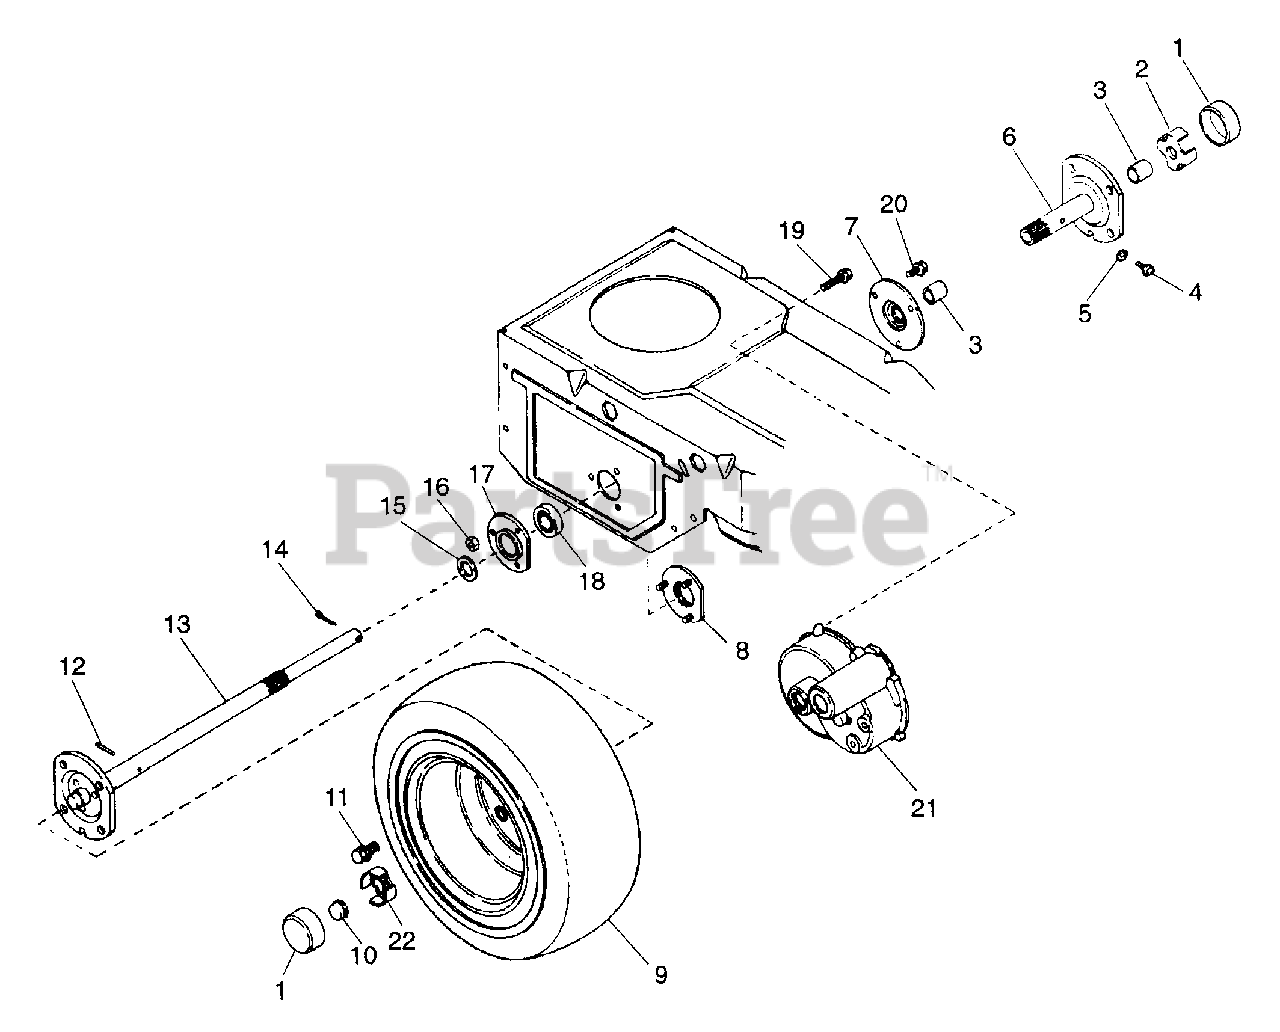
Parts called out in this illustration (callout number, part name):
1	HUB CAP
2	SPINDLE CUP
3	BSHG-SLV .690X.814X1.000 BR
4	SPIN DRIVE ZERK FITTING
5	WSHR-LK .250X.047 LT PL
6	L.H. AXLE ASSEMBLY
7	SEAL 1.125X2.496X.380
8	BEARING FLANGE
9	T/WHL ASSY 6.50-8 X 16
10	PUSHNUT
11	SCR-TAP .500-20X.62 HH PL
12	PIN-ROLL .188X1.25
13	RH AXLE
14	PIN-COTR .12X1.0 PL
15	WSHR-FL-STL .880X1.380X.062
16	NUT-LK-FLG .250-20 PL
17	BEARING FLANGE
18	BRG-BALL .876 X 1.750 X .50
19	SCR-TAP .312-18X1.50 HWH PL TR
20	SCR-TAP.250-20X.62 HWH BLK ZC
21	GEAR CASE ASSEMBLY
22	SPINDLE CUP
